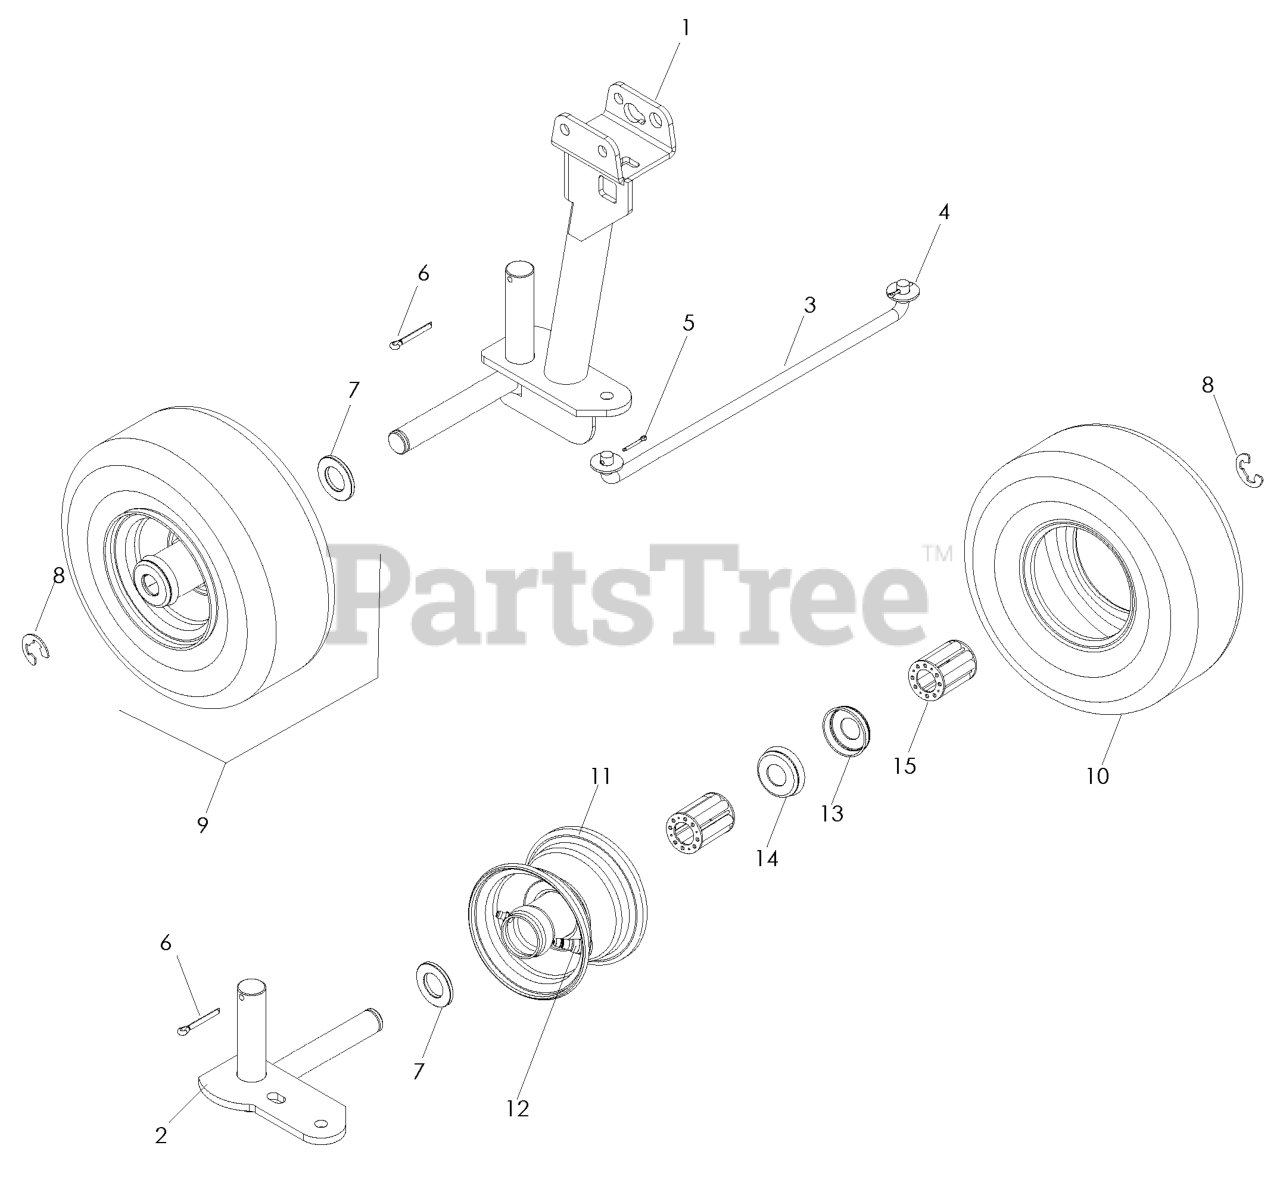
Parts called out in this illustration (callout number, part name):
1	ARM WELDMENT, RH, ORANGE
2	ARM WELDMENT, LH, ORANGE
3	STEERING ROD
4	WASHER 3/8 FLAT
5	COTTER PIN 3/32 X 3/4
6	COTTER PIN
7	WASHER 3/4 FLAT SAE ZD
8	E RING 3/4
9	TIRE/WHEEL.CASTER.9X3.5-4.SMOO
10	TIRE 9 X 3.5 - 4
12	VALVE STEM TR-412
13	ENDCAP
14	ENDCAP, NOTCHED
15	ROLLER BEARING
